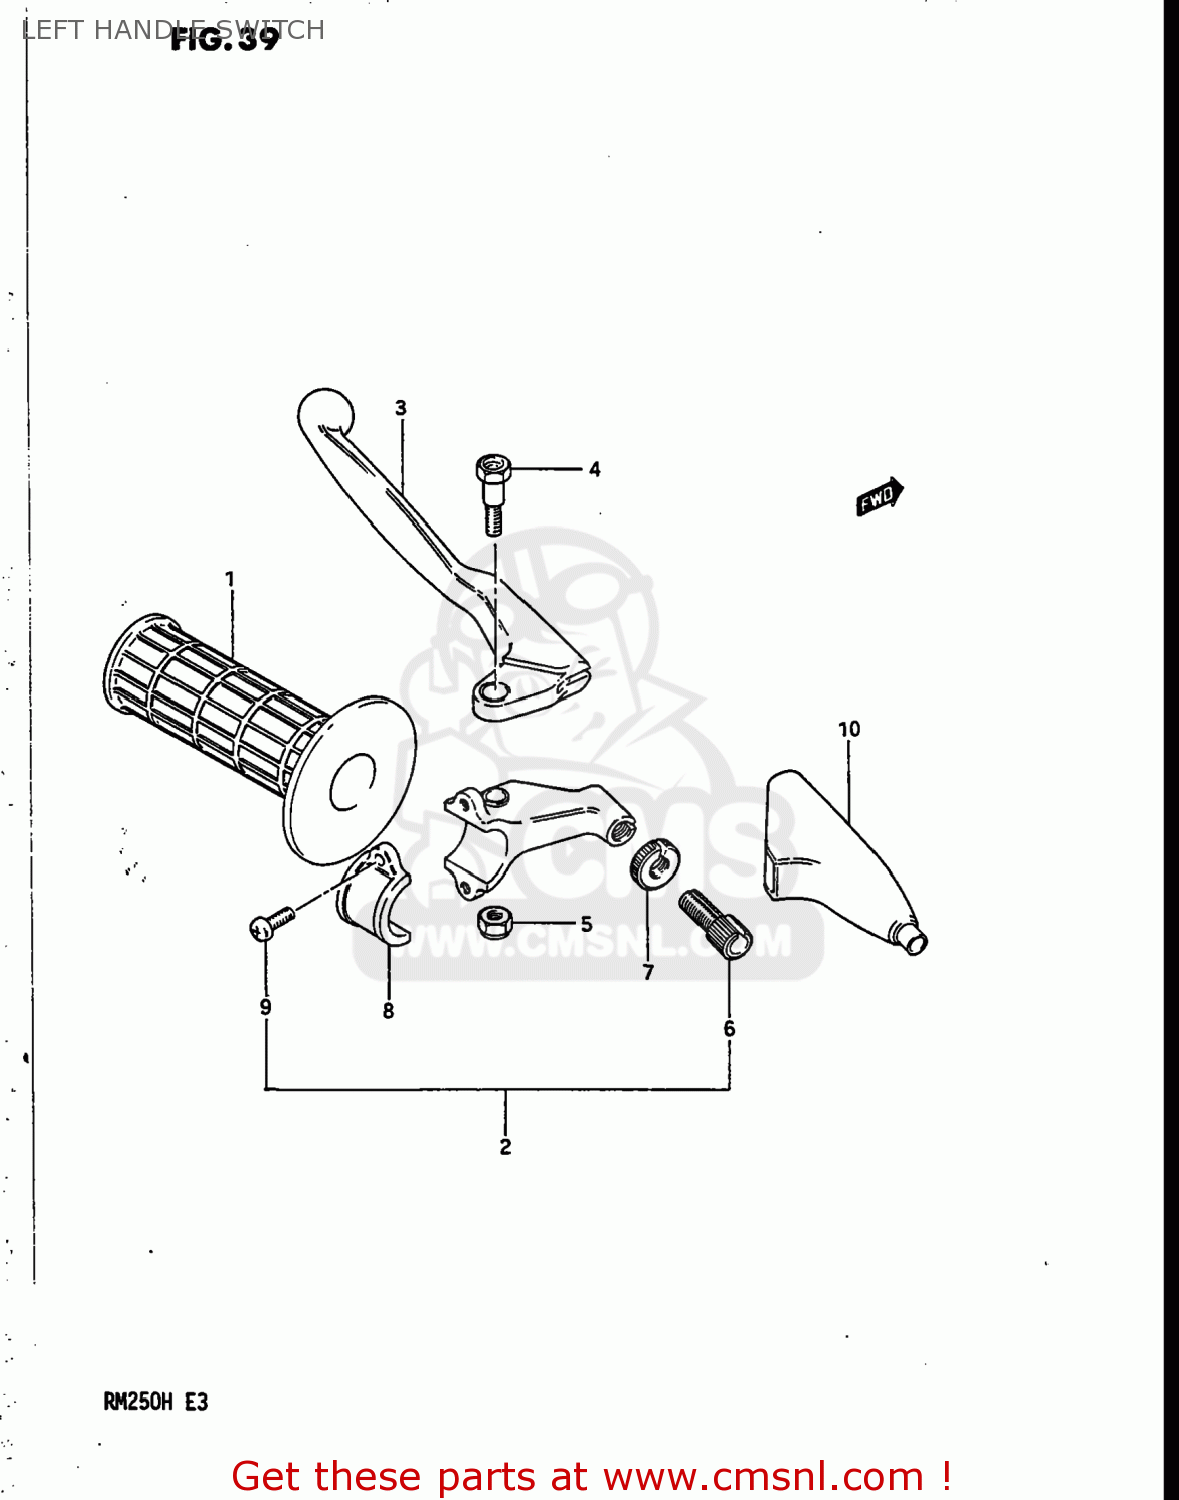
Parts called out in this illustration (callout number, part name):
1	GRIP,LEFT
2	LEVER ASSEMBLY
3	LEVER,CLUTCH
4	BOLT,LEVER
5	NUT
6	ADJUSTER,CABLE
7	NUT,CABLE ADJUSTER LOCK
8	HOLDER,LEVER
9	SCREW (5X14)
10	COVER,CLUTCH LEVER
